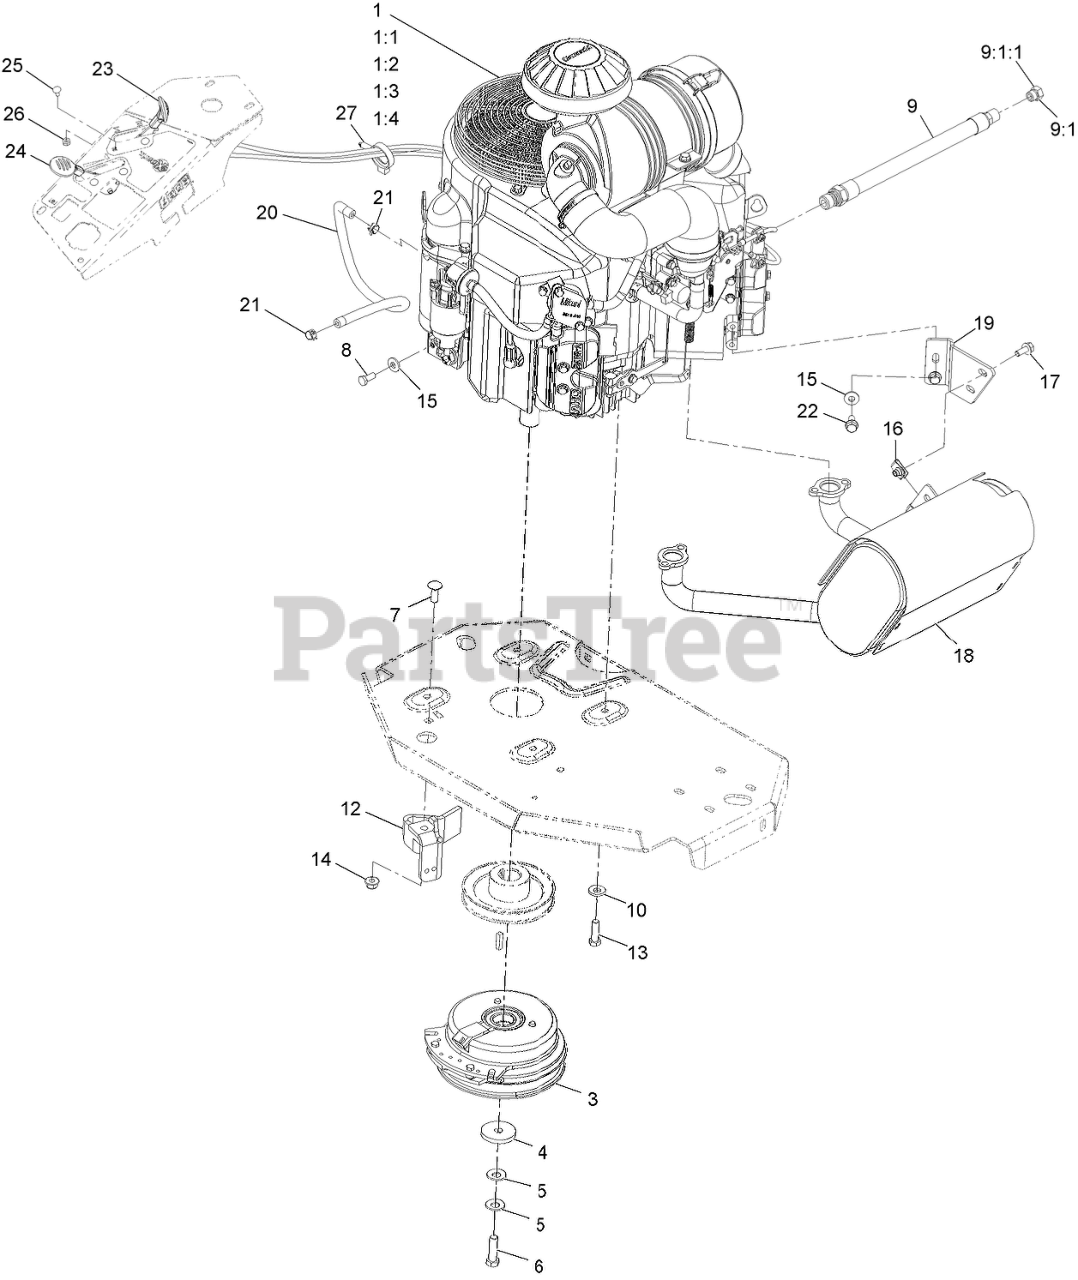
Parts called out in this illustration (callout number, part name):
1:1	Kawasaki 49065-2078 Engine Oil Filter
1:2	Kawasaki 49019-0031 Fuel Filter
1:3	Kawasaki 11013-7039 Safety Filter
1:4	Kawasaki 11013-7038 Air Filter
3	CLUTCH KIT
4	WASHER-CLUTCH
5	WASHER-SPRING
6	SCREW-HH 7/16-20 X 1 1/2 W/LOCTITE
7	SCREW-CARR
8	SCREW-HH
9	ENGINE OIL DRAIN HOSE ASM
9:1	PLUG-HH
9:1:1	O-RING
10	WASHER-BELLEVILLE
12	CLUTCH-ANCHOR
13	SCREW-HH
14	NUT-HF, NI
15	WASHER-SPRING
17	SCREW-HHF
18	KIT, MUFFLER
19	BRACKET-MUFFLER
20	HOSE-FUEL
21	CLAMP-HOSE
22	SCREW-HHF
23	ASM, CHOKE CABLE
24	ASM,THROTTLE CABLE
25	BOLT-CARR
26	NUT-LOCK, NI
27	CLAMP-HOSE
